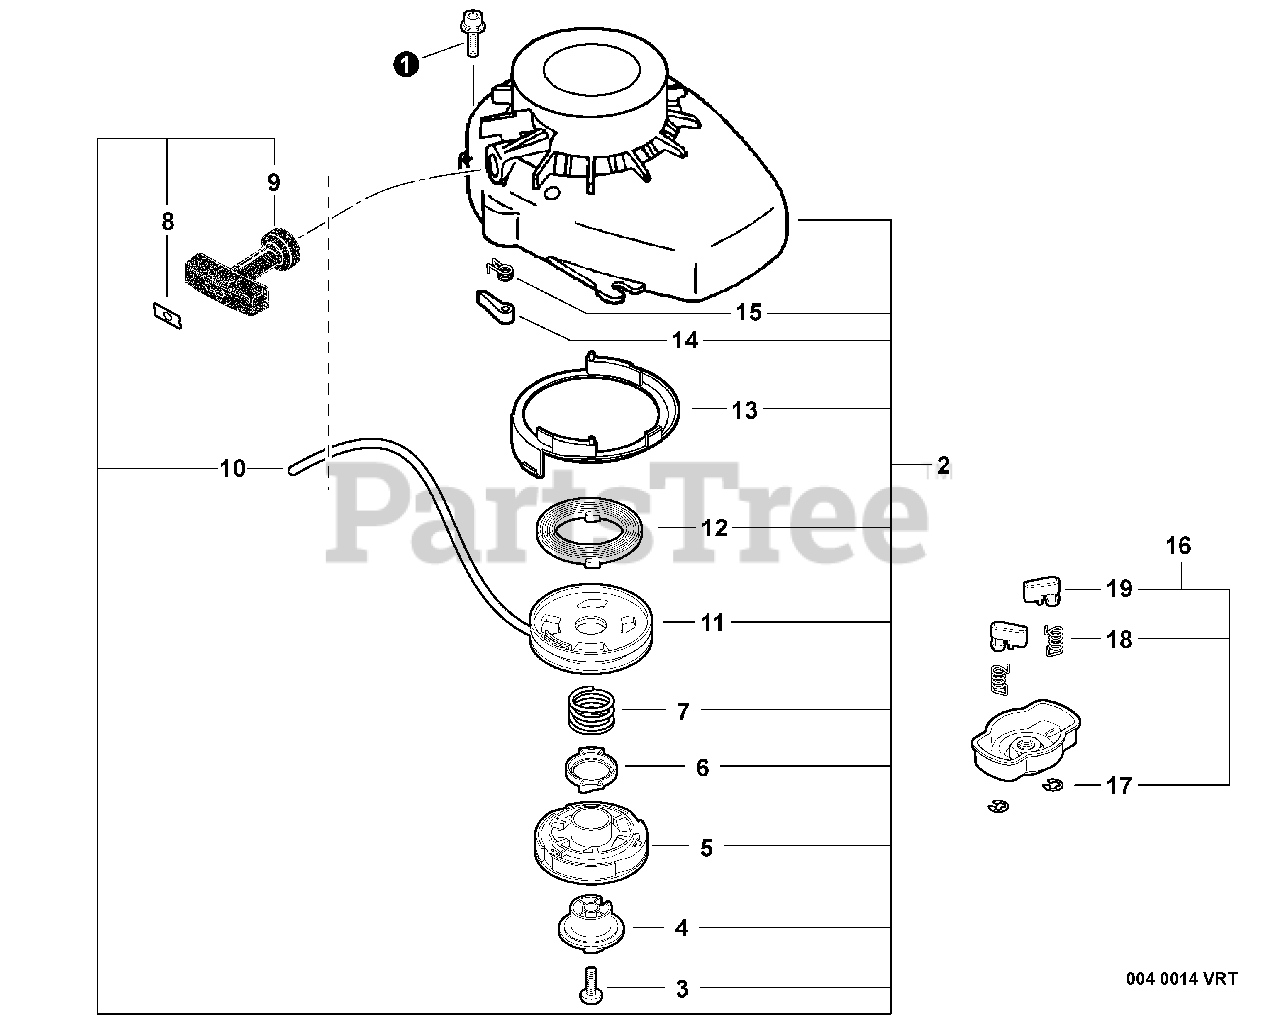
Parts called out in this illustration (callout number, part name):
1	BOLT 4×16
2	STARTER ASSY - ORANGE
4	PLATE, CAM
5	SPRING ASSY
6	PAWL, STARTER
7	SPRING, RETURN
8	RETAINER, ROPE
9	GRIP, STARTER
10	ROPE, STARTER
11	PULLEY, STARTER
12	SPRING, RECOIL
13	CASE, STARTER
14	PAWL, STARTER
16	PAWL ASSY, STARTER
17	E-RING 4
18	SPRING, RETURN
19	PAWL, STARTER
